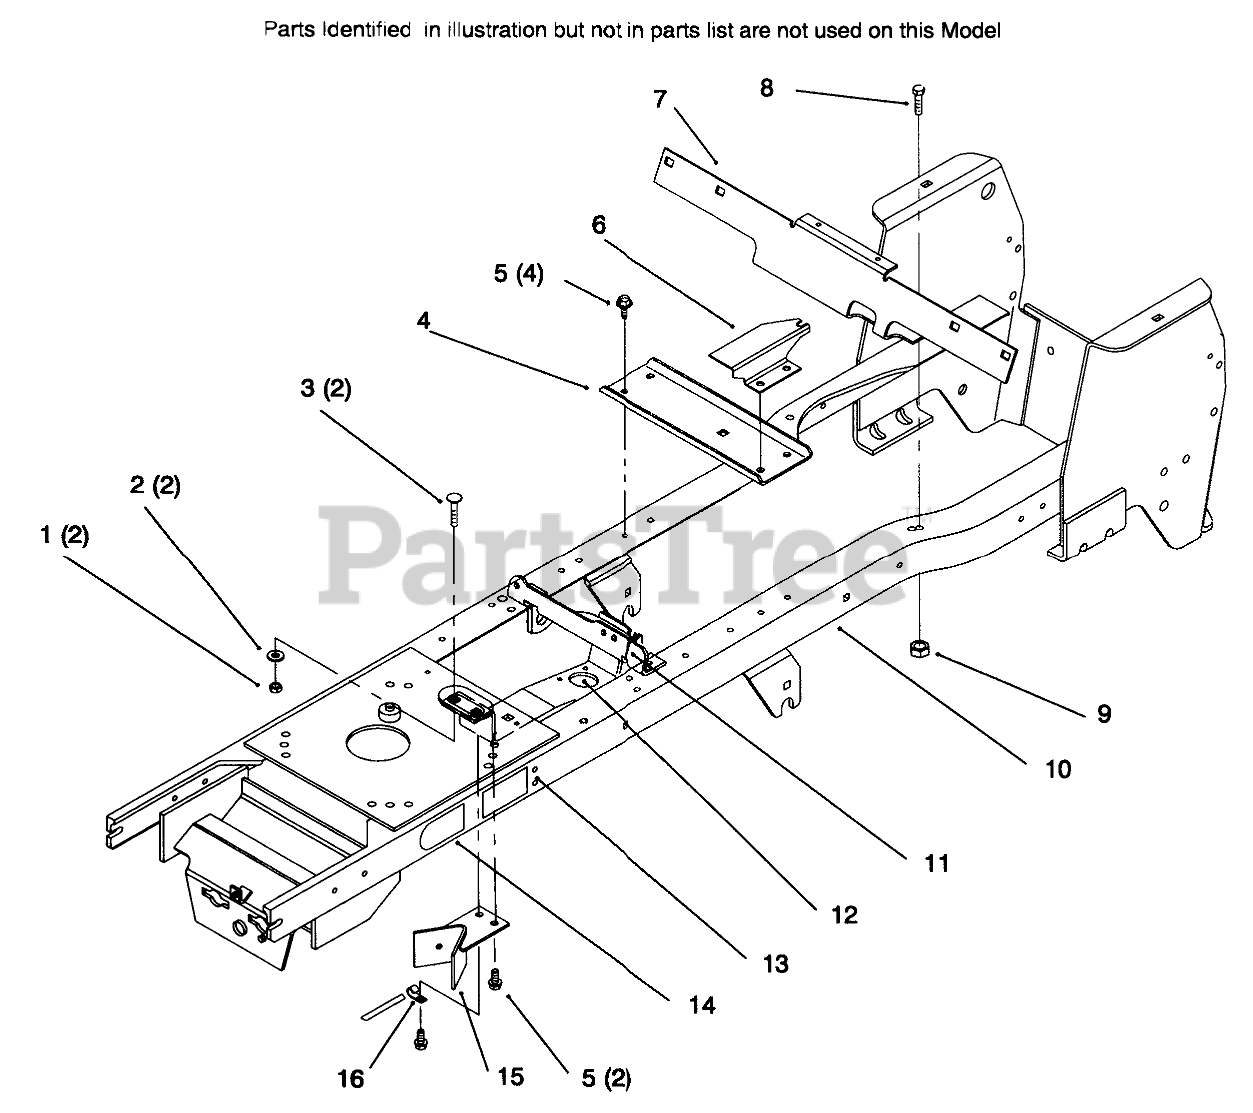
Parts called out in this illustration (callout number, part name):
1	NUT-LOCK, NI
2	WASHER-PLAIN
3	BOLT-CARR
4	BRACKET-IDLER PLATE
5	Screw-HH
6	BRACKET-HOC GAGE
7	SUPPORT - FENDER
8	SCREW-HH
9	NUT-LOCK, NI
10	Frame
11	TIE-CABLE
12	STEERING BRKT WA
13	Decal-Installation (Only On: 72104)
14	DECAL-ATTACH A-MATIC
15	WLDMT-PTO STOP
16	CLIP
